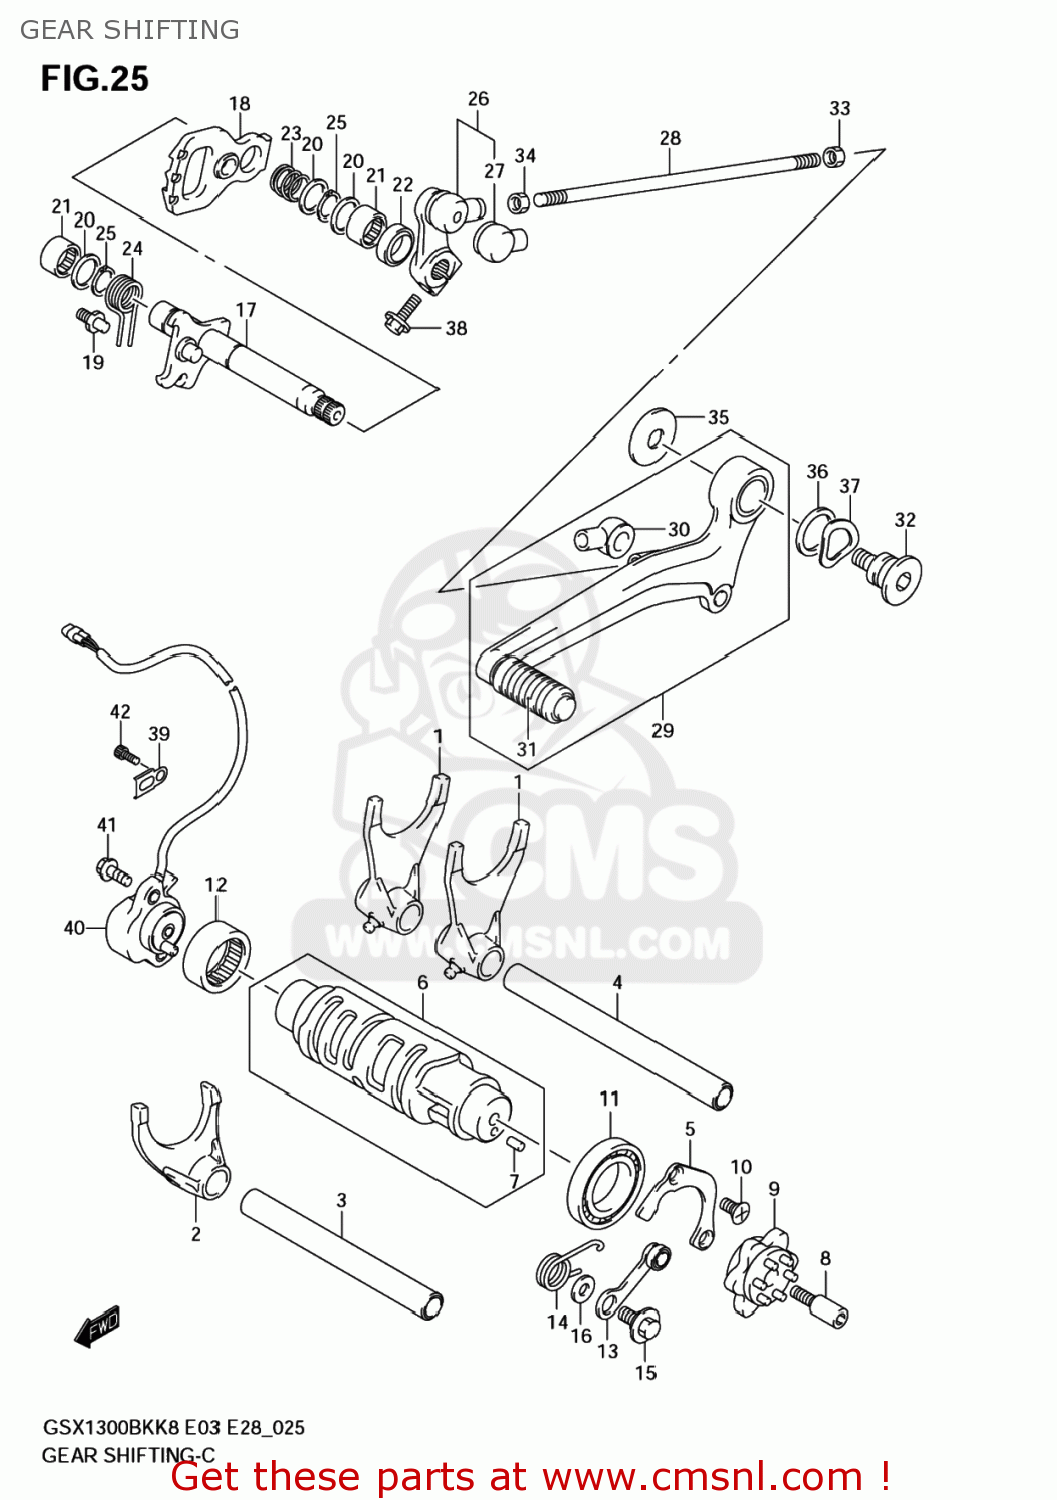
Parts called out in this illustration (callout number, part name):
1	FORK,GEAR SHIFT NO.1
2	FORK,GEAR SHIFT NO.3
3	SHAFT,SHIFT FORK NO.2(L:132)
4	SHAFT,GEAR SHIFT FORK(L:152)
5	RETAINER,SHIFT CAM BEARING
6	CAM,GEAR SHIFT
7	PIN
8	BOLT,GEAR SHIFT CAM PLATE
9	PLATE,GEAR SHIFT CAM
10	SCREW(6X12)
11	BEARING(25X47X8)
12	BEARING(25X32X12)
13	STOPPER,SHIFT CAM
14	SPRING,STOPPER ARM
15	BOLT(6X14.3)
16	WASHER
17	SHAFT,GEAR SHIFT
18	PLATE,GEAR SHIFT CAM DRIVE
19	STOPPER,GEAR SHIFT ARM
20	SHIM(14X22X1)
21	BEARING(14X20X12)
22	SEAL,OIL(14X22X6)
23	SPRING
24	SPRING
25	CIRCLIP
26	ARM,GEAR SHIFT LINK
27	COVER,DUST
28	ROD,GEAR SHIFT LINK
29	LEVER ASSY,GEA
30	COVER,DUST
31	RUBBER,GEAR SHIFT PEDAL
32	BOLT,GEAR SHIFT LEVER
33	NUT
34	NUT
35	WASHER(10X30X2.5)
36	WASHER(18X26X1)
37	WASHER
38	BOLT
39	CLAMP,GENERATOR LEAD WIRE
40	SENSOR. VERSNEL
41	BOLT
42	BOLT
